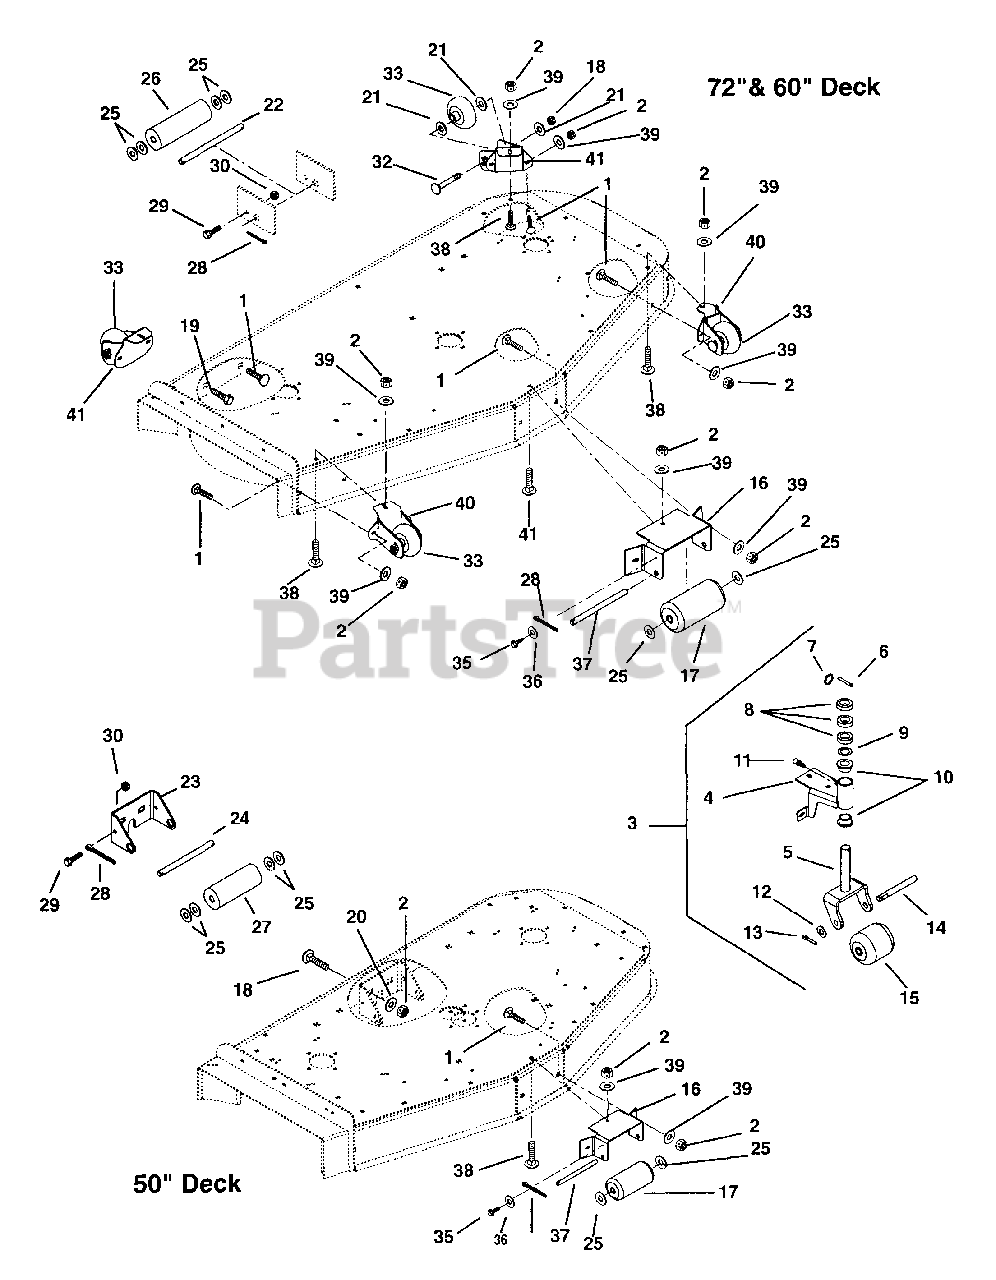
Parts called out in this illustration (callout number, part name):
1	Bolt-Round Head Square Neck .38-16 x 1.00 Grade 5
2	Nut-Locking-Nylon .38-16
3	Assembly, Roller Bracket
3	Assembly, Roller Bracket-Left Front
4	Weldment-Roller Bracket
4	Weldment-Roller Bracket-Left Front
5	Weldment-Roller Fork
6	Pin-Clevis .19 x 2.00
7	Kickout Ring
8	Bushing-Sleeve 1.04 x 1.75 x .500
9	Washer-Hardened Thrust 1.00 x 1.55 x .03
10	Bushing-Flange 1.020 x 1.385 x .75 x 1.75
11	Fitting-Lube .25-28 Taper
12	Washer-Flat Steel .656 x 1.31 x .095
13	Pin-Cotter .25 x 1.00
14	Shaft, Castor
16	Bracket, Anti-Scalp Roller
18	Nut-Locking-Nylon .50-13
19	Bolt-Hex .38-16 x 1.00 Grade 5
20	Washer-Flat-Steel .38 x .875 x .083
21	Washer-Flat-Steel .531 x 1.06 x .095
22	Shaft, Center Roller
23	Bracket, Roller
24	Rod
25	Washer-Flat-Steel .656 x 1.31 x .095
26	Roller, Gage
27	Roller, Gage
28	Pin-Cotter .25 x 2.00
29	Bolt-Hex .25-20 x .75 Grade 5
30	Nut-Locking-Center .25-20
31	Bolt-Hex .31-18 x 1.00 Grade 2
32	Bolt-Round Head Square Neck .50-13 x 5.00 Grade 2
33	Wheel, 3 x 5
35	Screw-Self Tapping .25-20 x .50 x Hex Washer Head
36	Washer-Flat-Steel
38	Bolt-Round Head Square Neck .38-16 x 1.25 Grade 5
39	Washer-Flat-Steel .406 x .812 x .065
40	Weldment-Left Front Roller Bracket
40	Weldment-Right Front Roller Bracket
41	Weldment-Wheel Support Left Hand
41	Weldment-Wheel Support Right Hand
